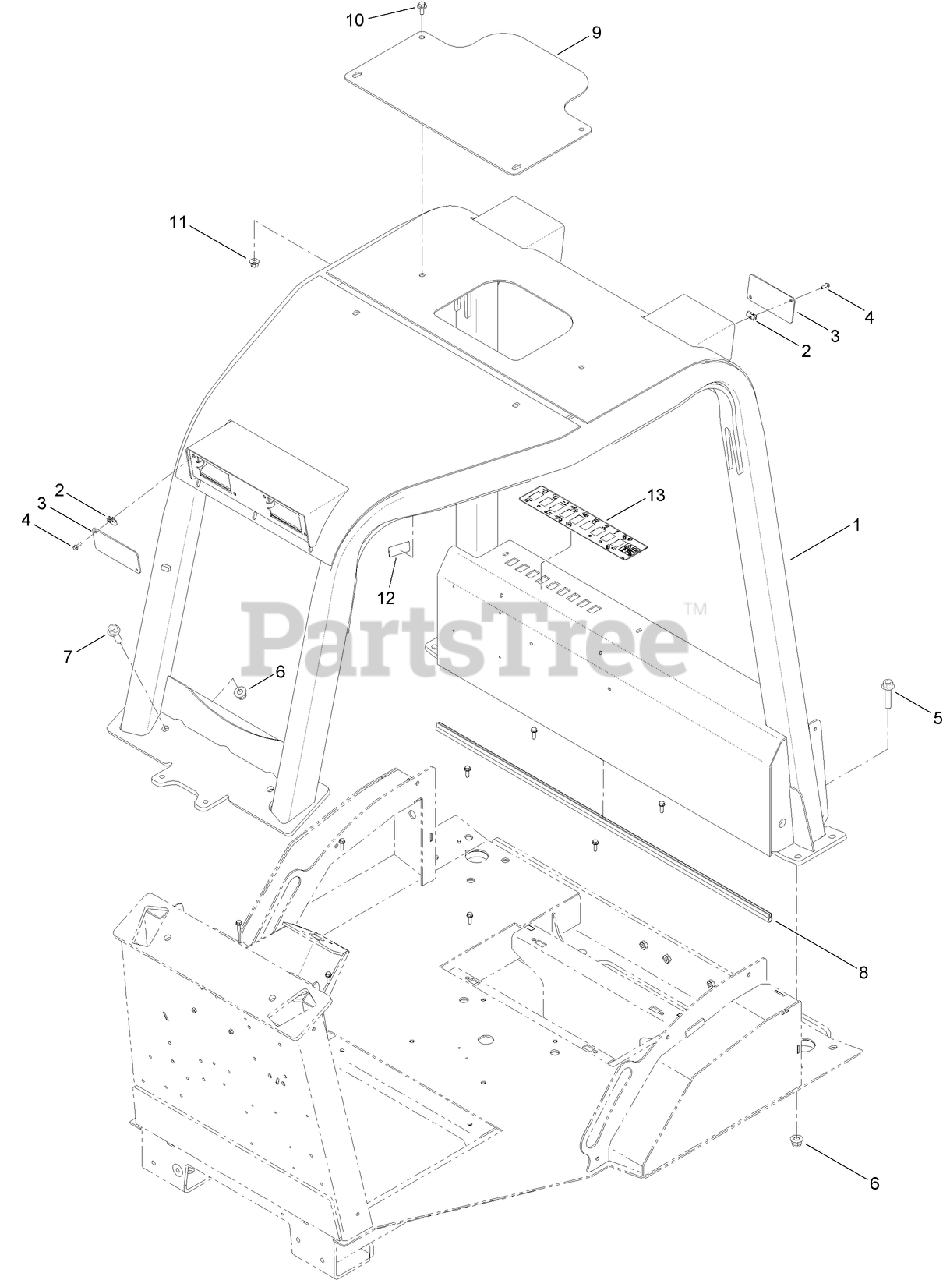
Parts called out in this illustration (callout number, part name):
1	MAIN ROPS ASM
3	PLATE-COVER
4	SCREW-HHF
5	SCREW-FLANGE
6	NUT-HHF
7	SCREW-FLANGE
8	SEAL-HOOD
9	COVER-ROPS
10	SCREW-HHF
11	NUT-LOCK, HHF
12	DECAL-ROPS
13	DECAL-SWITCHES, REAR CONTROL
